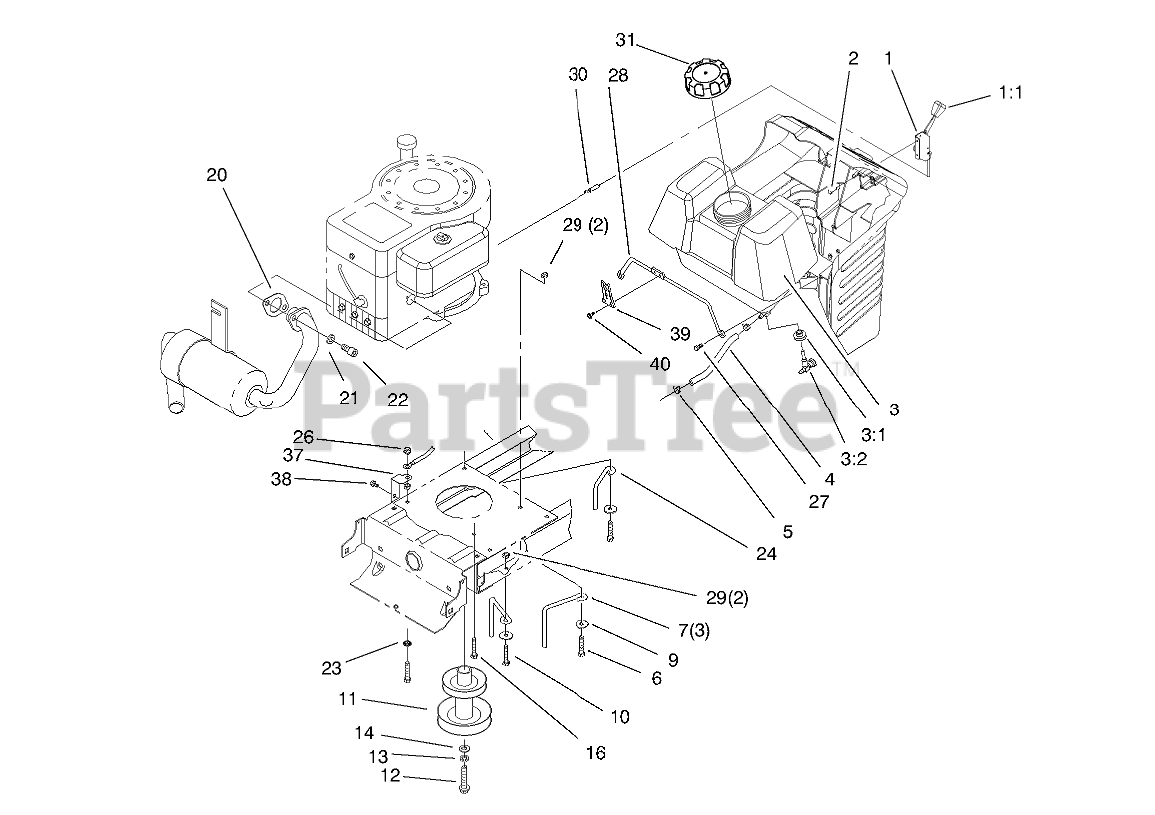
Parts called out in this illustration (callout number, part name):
1	THROTTLE CONTROL ASM
2	SCREW-SPECIAL
3	GAS TANK ASM
3:1	BUSHING
3:2	VALVE-FUEL
4	HOSE-FUEL
5	CLAMP-HOSE
6	SCREW-HH
7	GUIDE-BELT, ENGINE
9	WASHER-PIVOT
10	SCREW-HH
11	PULLEY-ENGINE ASM
12	SCREW-HH
13	WASHER-LOCK
14	WASHER-FLAT
16	SCREW-HWH, TAPTITE
20	GASKET-EXHAUST
21	WASHER-LOCK
22	SCREW-HSH
23	WASHER-LOCK
24	GUIDE-BELT, RH
26	NUT-KEPS
27	SCREW-SPECIAL
28	ROD-TANK, GAS
29	NUT-LOCK, NI
30	THROTTLE CABLE ASM
31	GAS CAP ASM
37	BRACKET-GROUND
38	SCREW-HWH
39	LATCH-HOOD
40	SCREW-HWH
